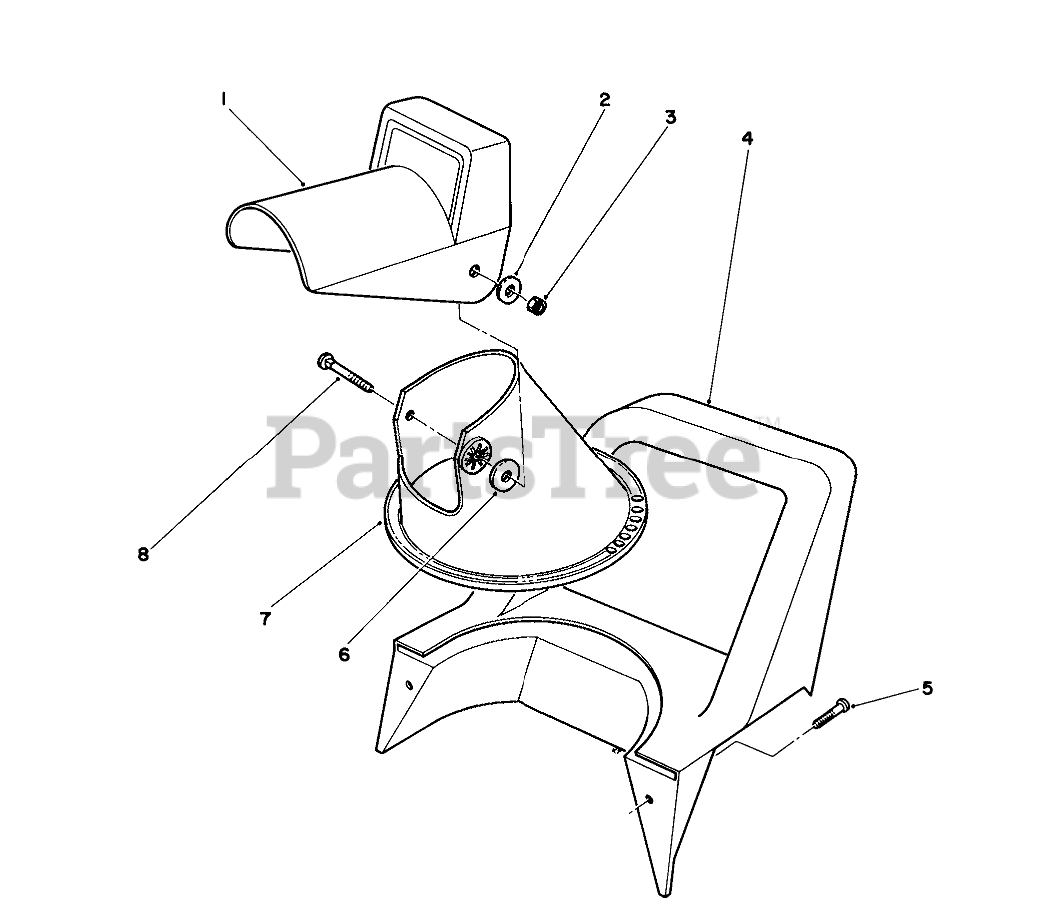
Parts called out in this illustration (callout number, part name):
1	Chute-Deflector
2	WASHER-FLAT
3	NUT-LOCK, NI
4	Handle-Middle
5	Screw
6	WASHER-RUBBER
7	Chute-Lower
8	BOLT-CARR
